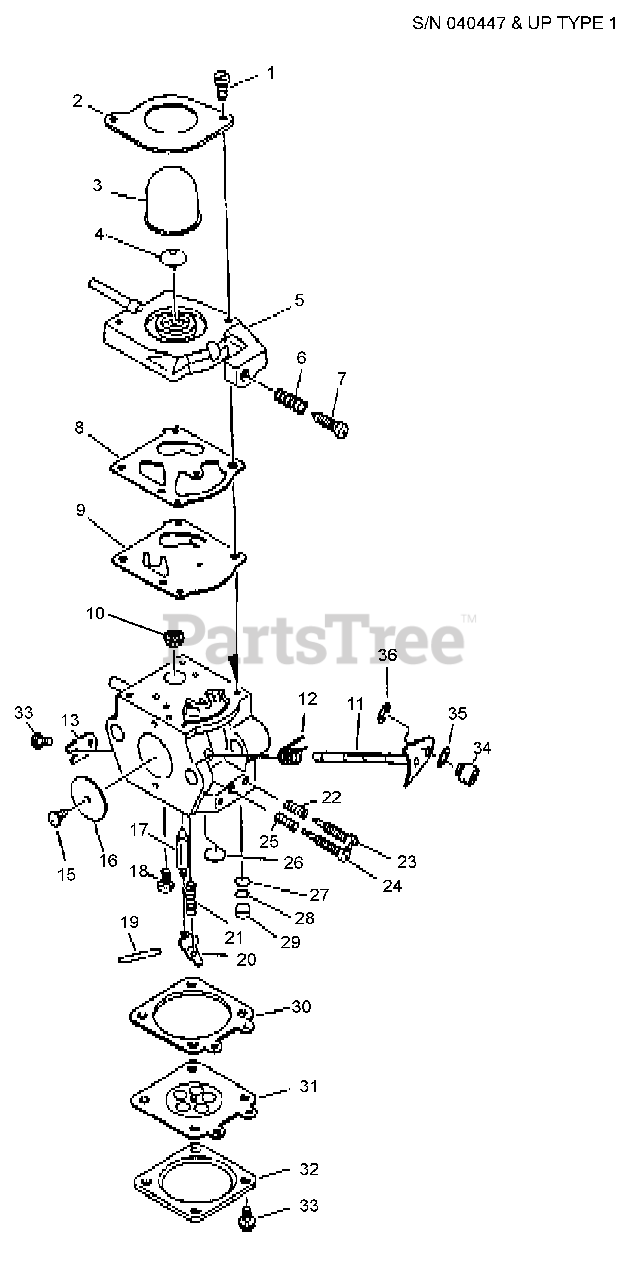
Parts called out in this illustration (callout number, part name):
1	SCREW
2	RETAINER, PURGE BULB
3	BULB, PURGE
4	VALVE, CHECK
5	COVER, PUMP
6	SPRING, IDLE ADJUST
7	SCREW, IDLE ADJUST
8	GASKET, PUMP
9	DIAPHRAGM, PUMP
10	STRAINER
11	SHAFT, THROTTLE
12	SPRING, THROTTLE RETURN
13	CLIP, THROTTLE SHAFT
16	VALVE, THROTTLE
17	VALVE, INLET NEEDLE
18	SCREW, METERING LEVER PIN
19	PIN, METERING LEVER
20	LEVER, METERING
21	SPRING, METERING LEVER
22	SPRING
23	NEEDLE - HIGH SPEED
24	NEEDLE - LOW SPEED
25	SPRING
26	PLUG, WELCH
27	STRAINER
28	RING, RETAINING
29	PLUG, WELCH
30	GASKET, METERING
31	DIAPHRAGM, METERING
32	COVER, PUMP
33	SCREW
36	RING, RETAINING
